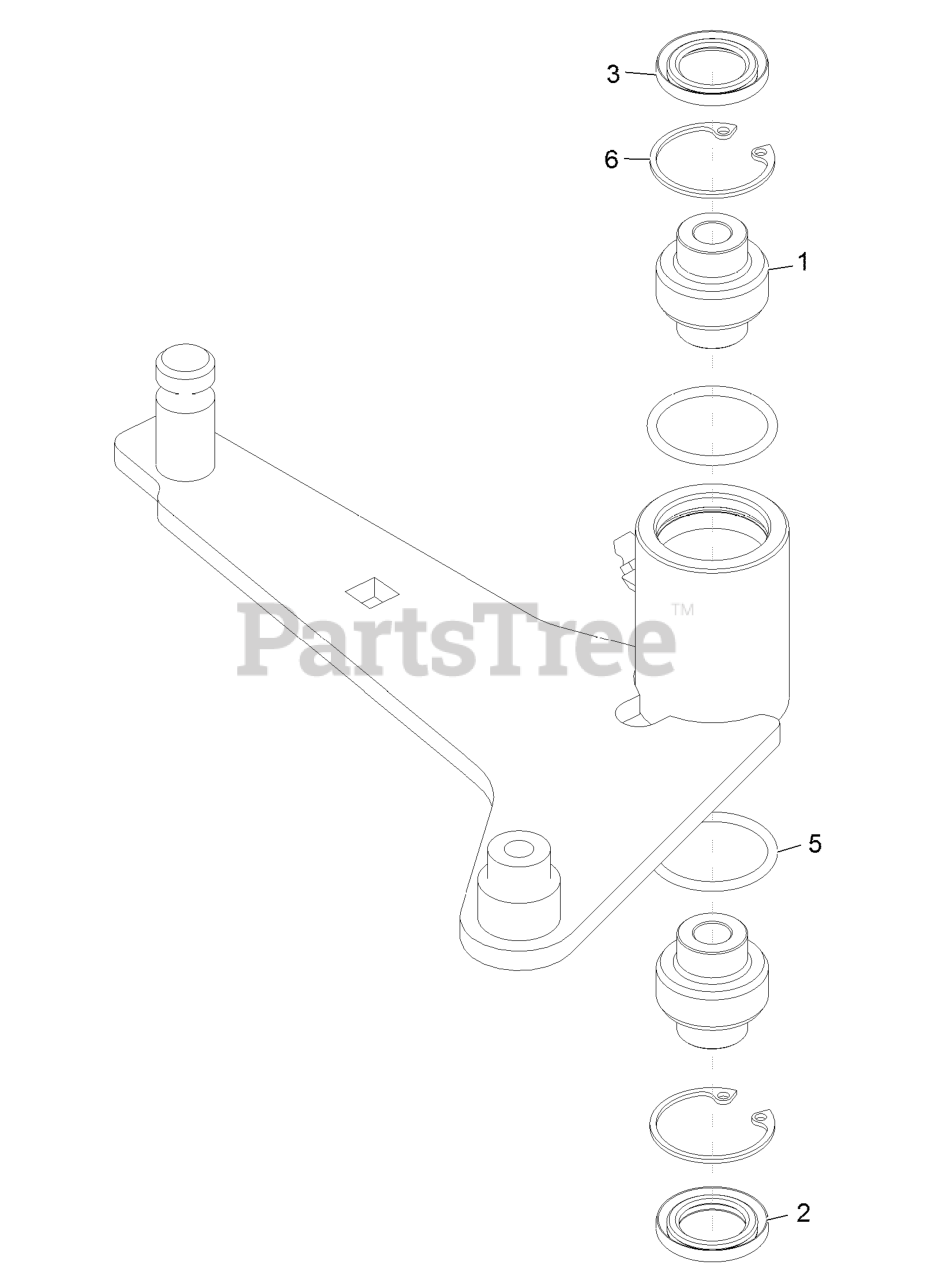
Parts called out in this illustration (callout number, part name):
1	BEARING-SPHERICAL
2	SEAL-LIP, DOUBLE
3	SEAL-LIP, SINGLE
6	RING-SNAP
